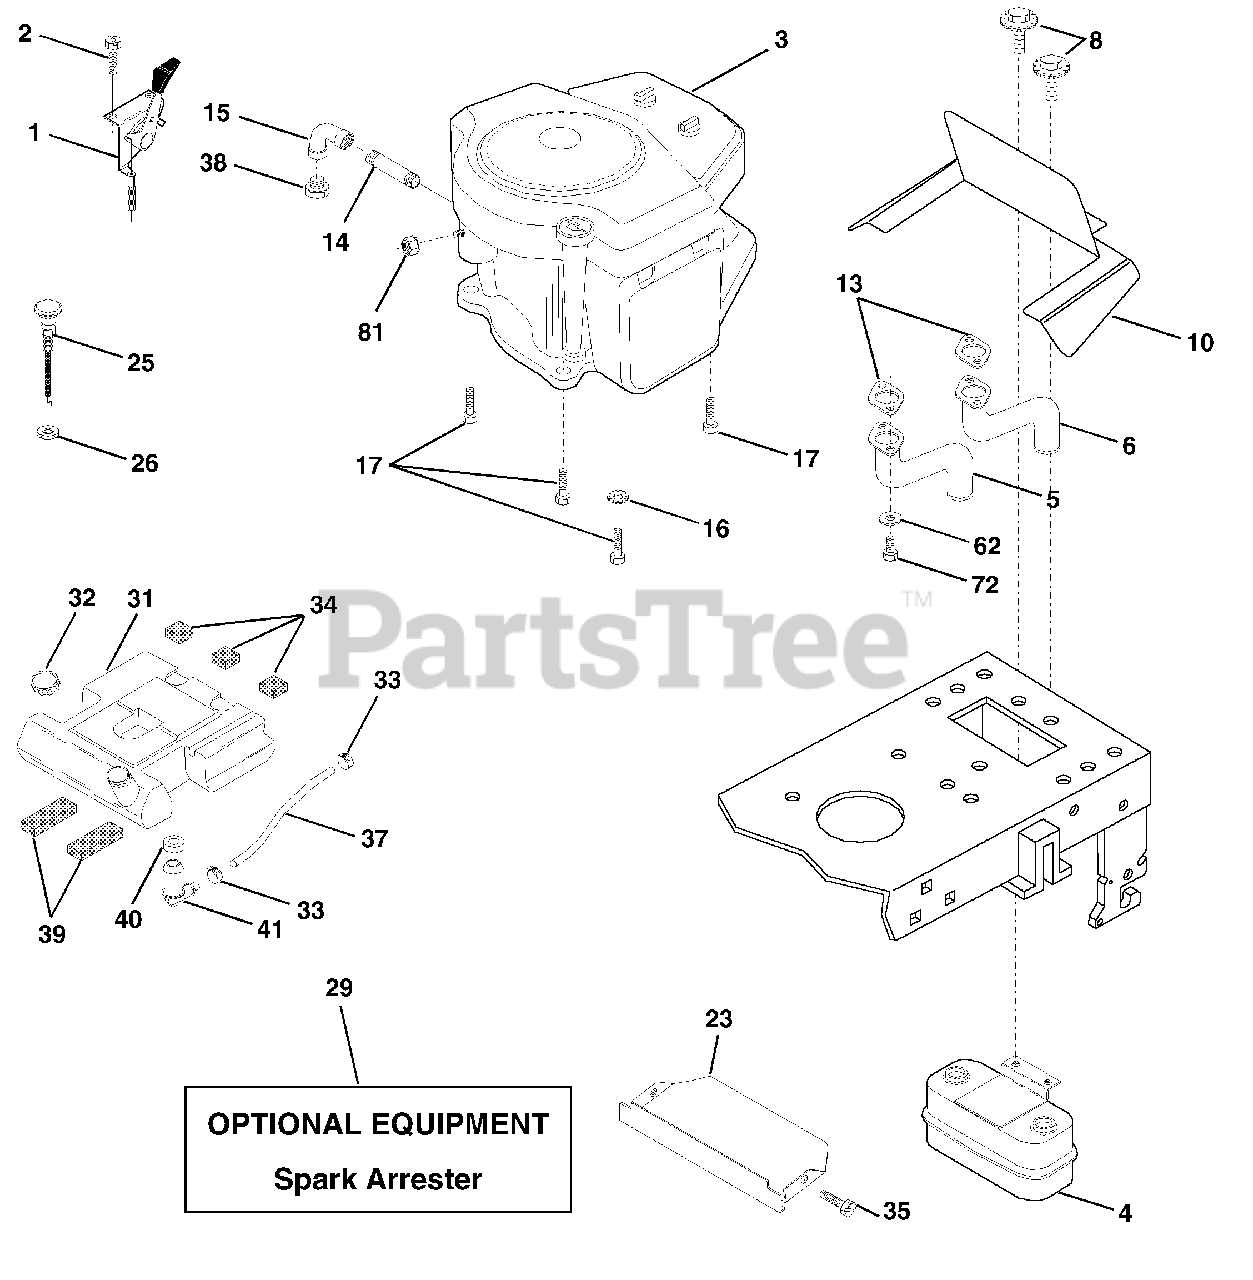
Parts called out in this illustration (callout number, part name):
1	Control, Throttle
2	Screw, Hex Head, Thread Cutting 1/4-20 x 5/8
5	Tube, Manifold, LH
6	Tube, Manifold, RH
8	Bolt 5/16-18 UNC x 3/4 w/Sems
10	Shield, Browning
13	Muffler Gasket
14	Nipple, Pipe 3/8 NPT x 4-1/2
15	Elbow, Standard 90° 3/8-18 NPT
16	Washer, Lock, External Tooth 3/8
17	Screw Thdrol 3/8-16 x 1-1/2
23	Shield, Browning / Debris Guard
25	Choke Control
26	Nut, Keps 3/8-24 UNF
29	Kit, Spark Arrestor
31	Tank Fuel 3 50 Rear
32	Cap Asm Fuel W/sym Vented
33	Clamp, Hose
34	Pad, Spacer
35	Screw, Thd. Roll. 5/16-18 x 3/4
37	Line, Fuel
38	Plug, Oil Drain
39	Pad, Idler
41	Stem, Fuel Tank
62	Washer, Lock 5/16
72	Screw, Hex Socket Head 5/16-18 x
81	Nut, Flange 1/4-20 Starter Nut
